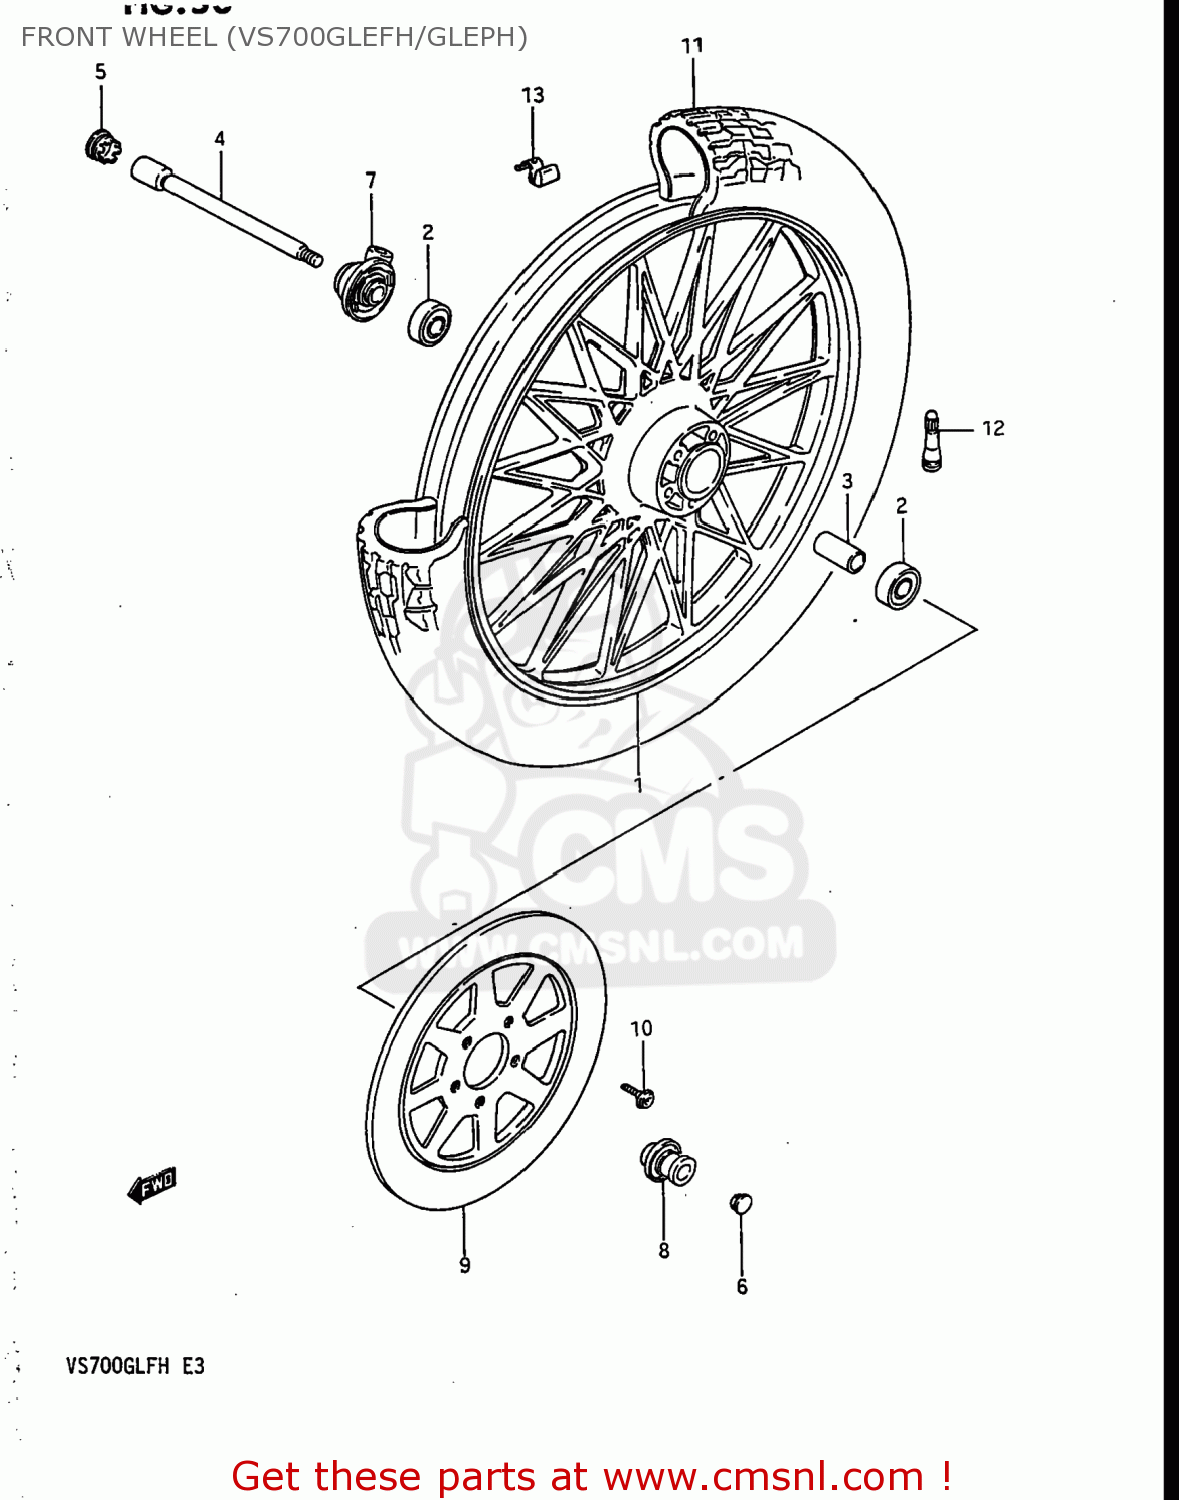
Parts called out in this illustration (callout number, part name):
1	CASTING WHEEL,FRONT 2.15-
2	BEARING
3	SPACER(15.3X21.7X65)
4	AXLE,FRONT
5	CAP,FR AXLE
6	CAP,FRONT AXLE
7	BOX ASSY,SPEEDOMETER GEAR
8	SPACER COMP,FRONT AXLE
9	DISC,FRONT BRAKE
10	BOLT(8X25.5)
11	TIRE,FRONT
12	VALVE,TIRE
13	BALANCER,WHEEL
